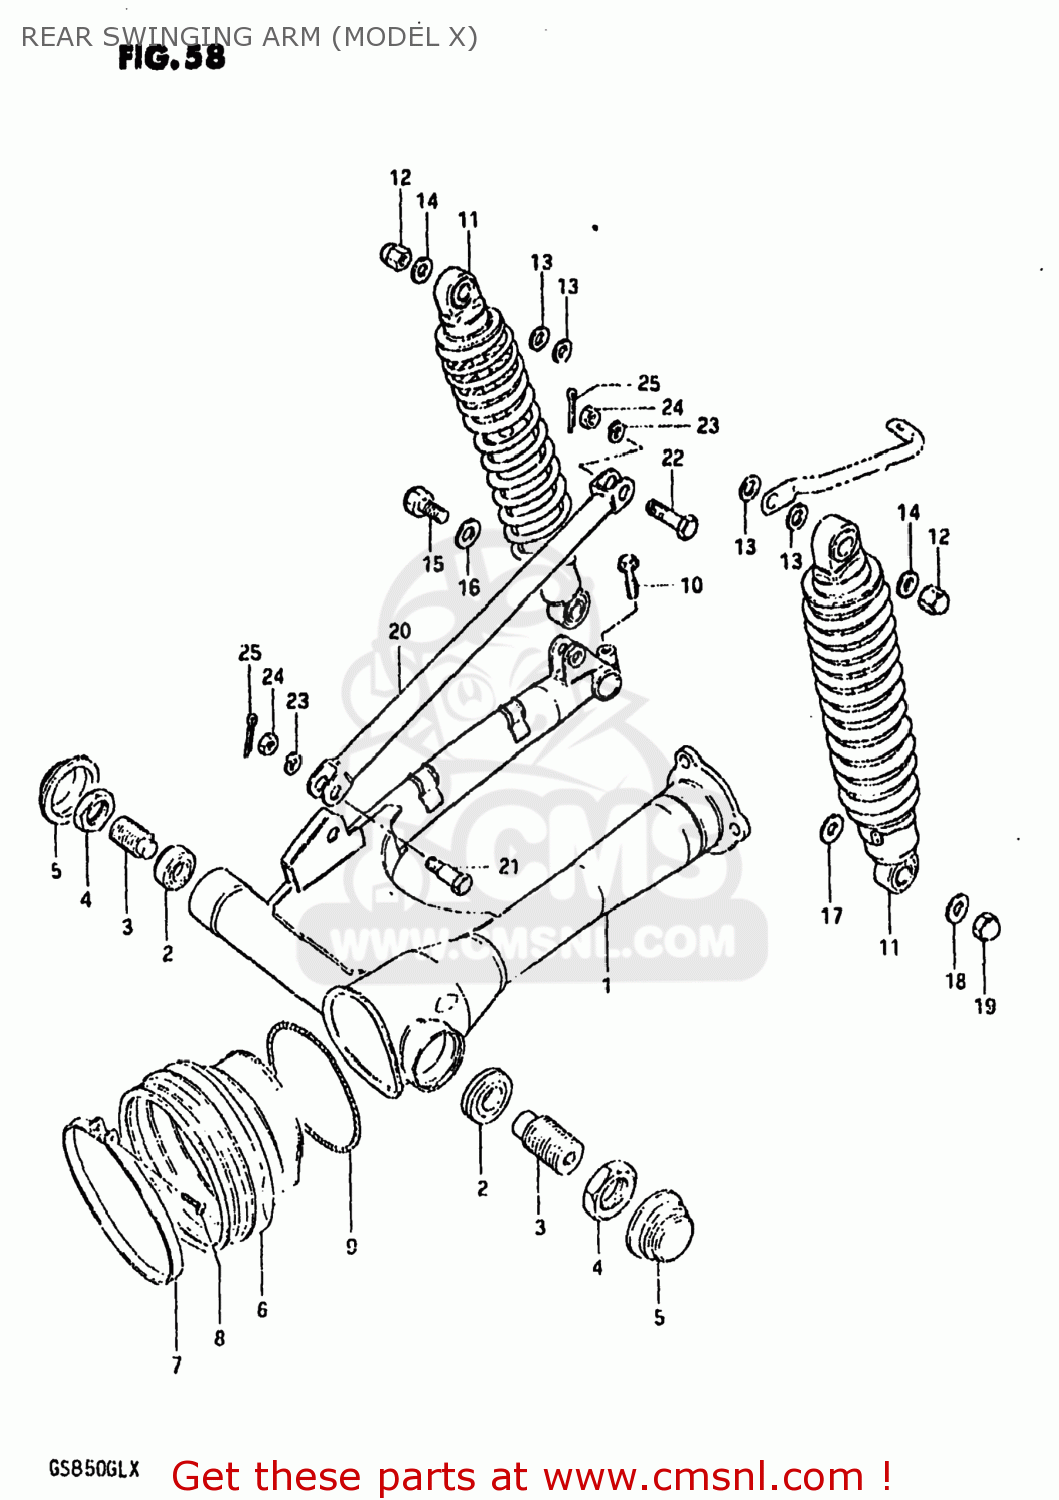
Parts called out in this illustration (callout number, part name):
1	SWING ARM SET,REAR (B
2	BEARING(17X40X13.25)
3	BOLT,REAR SWING ARM PIVOT
4	NUT
5	CAP,REAR SWING ARM PIVOT
6	BOOT,PROPELLER SHAFT
7	CLAMP
8	SCREW 4X25
9	SPRING,PROPELLER SHAFT
10	BOLT
11	ABSORBER ASSEMBLY,REAR SHOCK
12	NUT
13	WASHER
14	WASHER
15	BOLT 12X33
16	WASHER (12.5X24X1.6)
17	WASHER
18	WASHER
19	NUT, LOWER LH
20	TORQUE LINK,REAR
21	BOLT
22	BOLT(10X39)
23	WASHER
24	NUT
25	PIN 20X20
